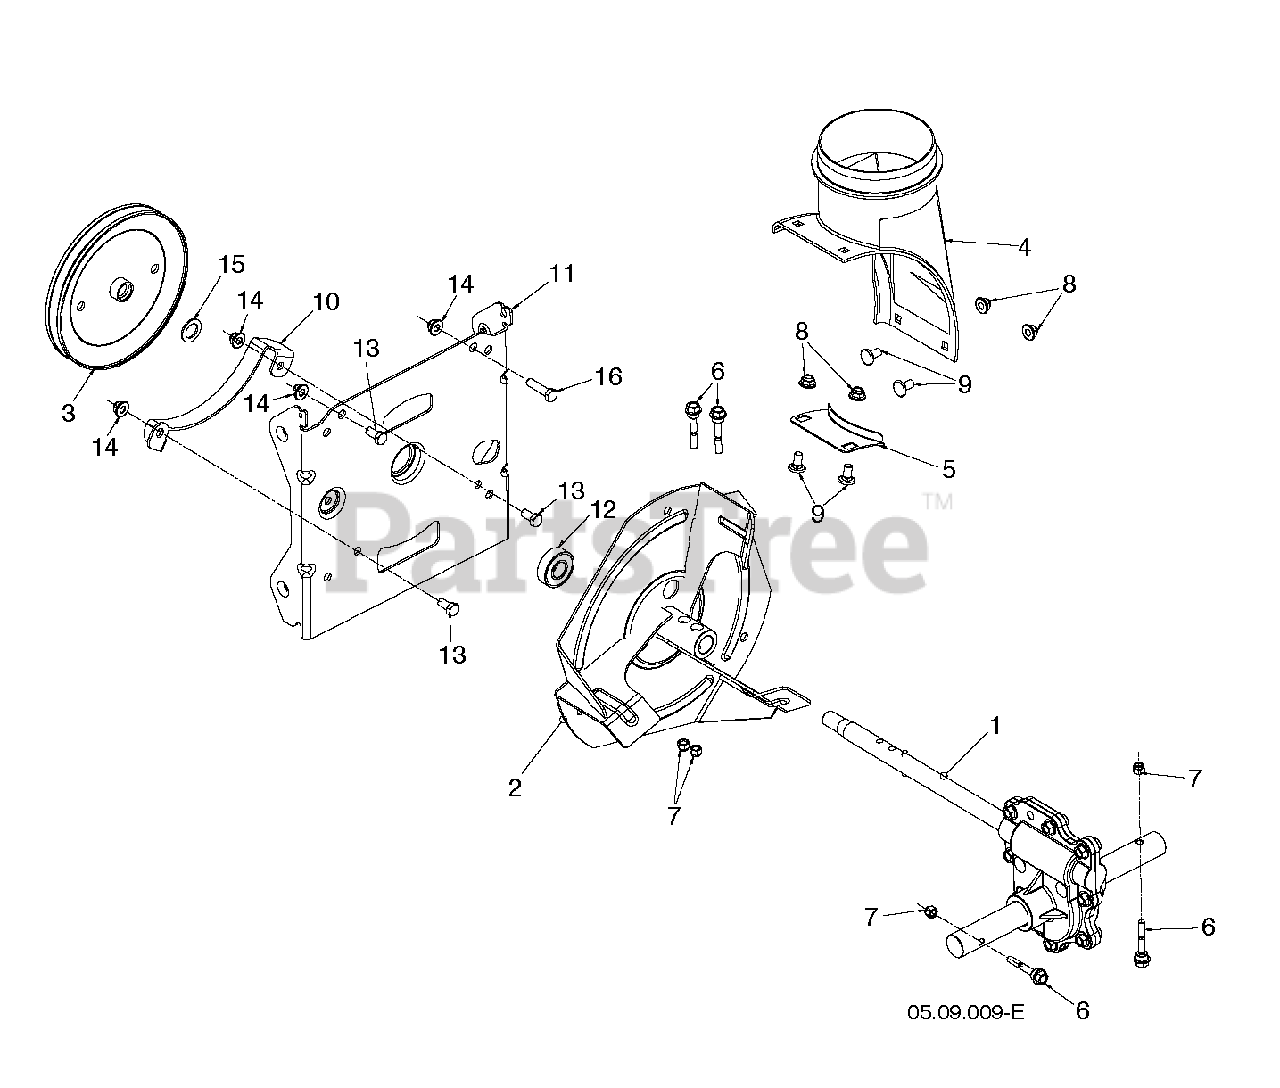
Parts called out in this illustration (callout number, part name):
1	Gear Box Assembly Alum
2	Impeller, Steel Snow Black
3	Screw-on Pulley, 7.3
4	Discharge Chute Base
5	BRACKET, CORNER DISCHARGE
6	Hex Head Shear Bolt, 1/4-20 X 1-13/16
7	LOCKNUT.NYLOC.1/4-20
8	Flange Hex Nut, Nylock Blk 5.16-1
9	Carriage Wafer Bolt, 5/16-18
10	BRACKET.BELT.KEEPER.LOWER.BLAC
11	Auger Housing Inter Bracket, Black
13	BOLT, HEX HEAD 5/16-18
14	NUTNYLOK.FLRANGE.5/16-18
15	Impeller Pulley Washer
16	BOLT.5/16-18X1-1/4 FULL THD
